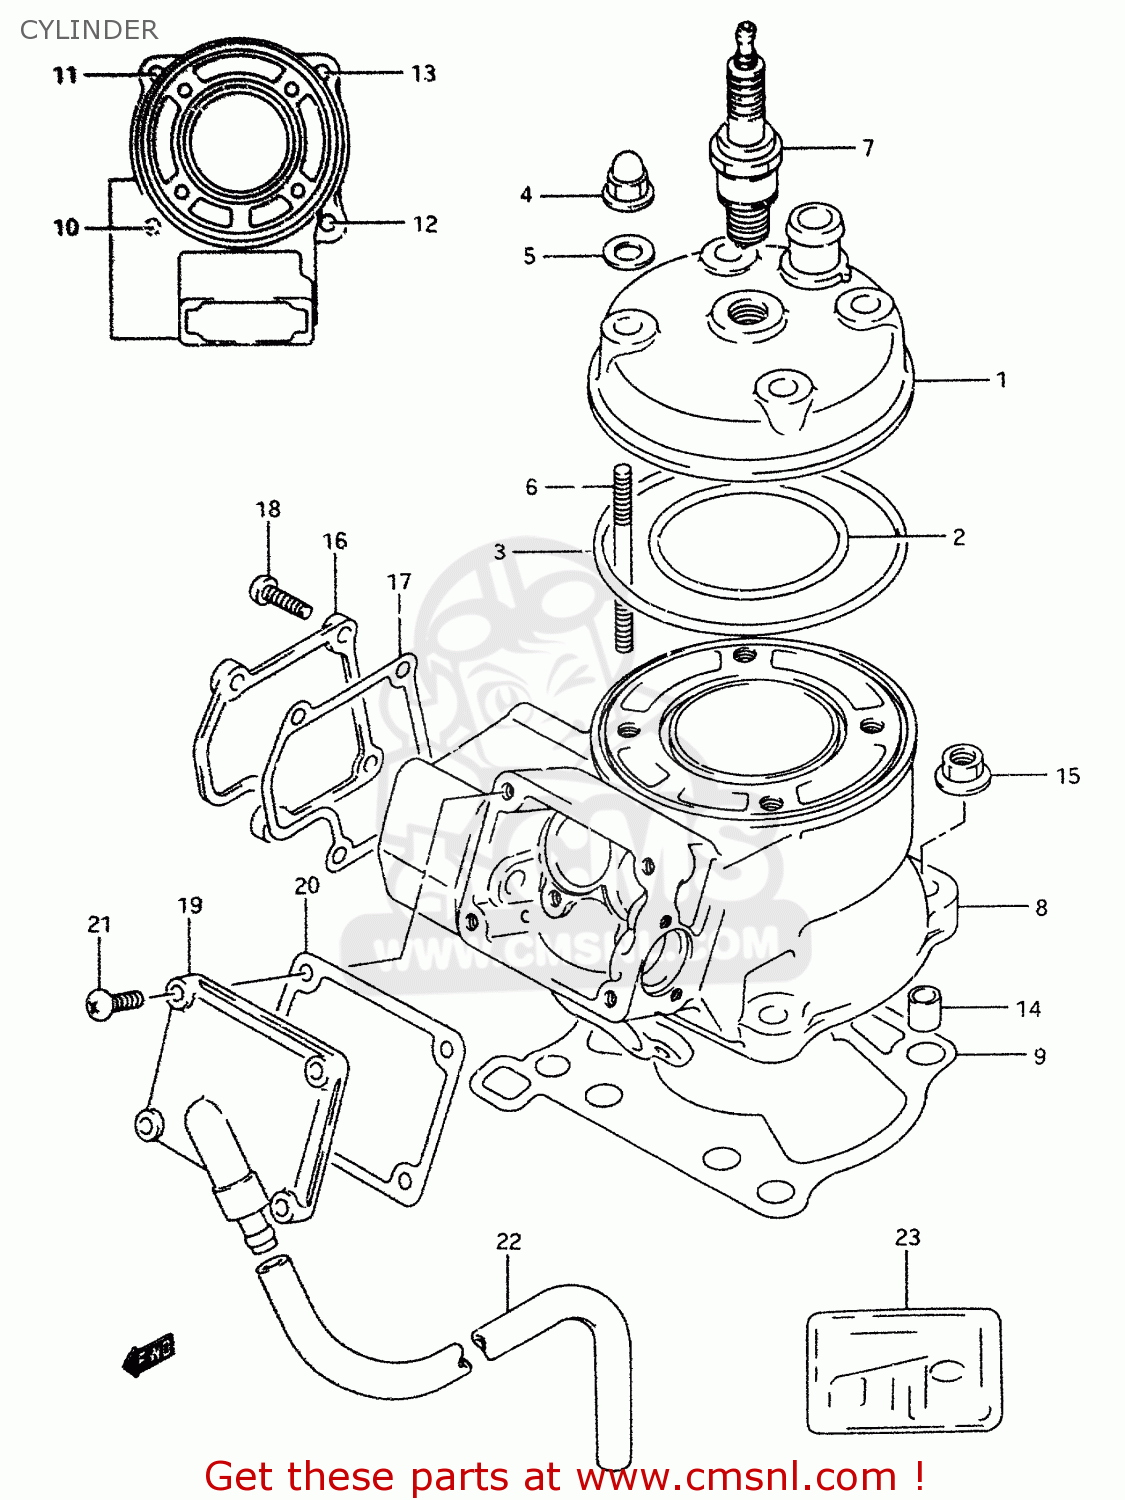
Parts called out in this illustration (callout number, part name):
1	HEAD,CYLINDER
2	O RING,CYLINDER HEAD NO.1
3	O RING,CYLINDER HEAD NO.2
4	NUT
5	GASKET(8.5X17X2.3) (NAS)
6	BOLT,STUD
7	PLUG,SPARK(BR10ES)
8	CYLINDER COMP
9	GASKET,CYLINDER (NAS)
10	BOLT,STUD
11	STUD 8X25
12	BOLT,STUD
13	BOLT,STUD
14	PIN(8.4X11X14)
15	NUT
16	COVER,CYLINDER NO.1
17	GASKET,CYLINDER COVER NO.1 (NAS)
18	SCREW
19	COVER,CYLINDER
20	GASKET,CYL COVER NO.2 (NAS)
21	SCREW
22	HOSE(7X12X600)
23	GASKET SET (NAS)
